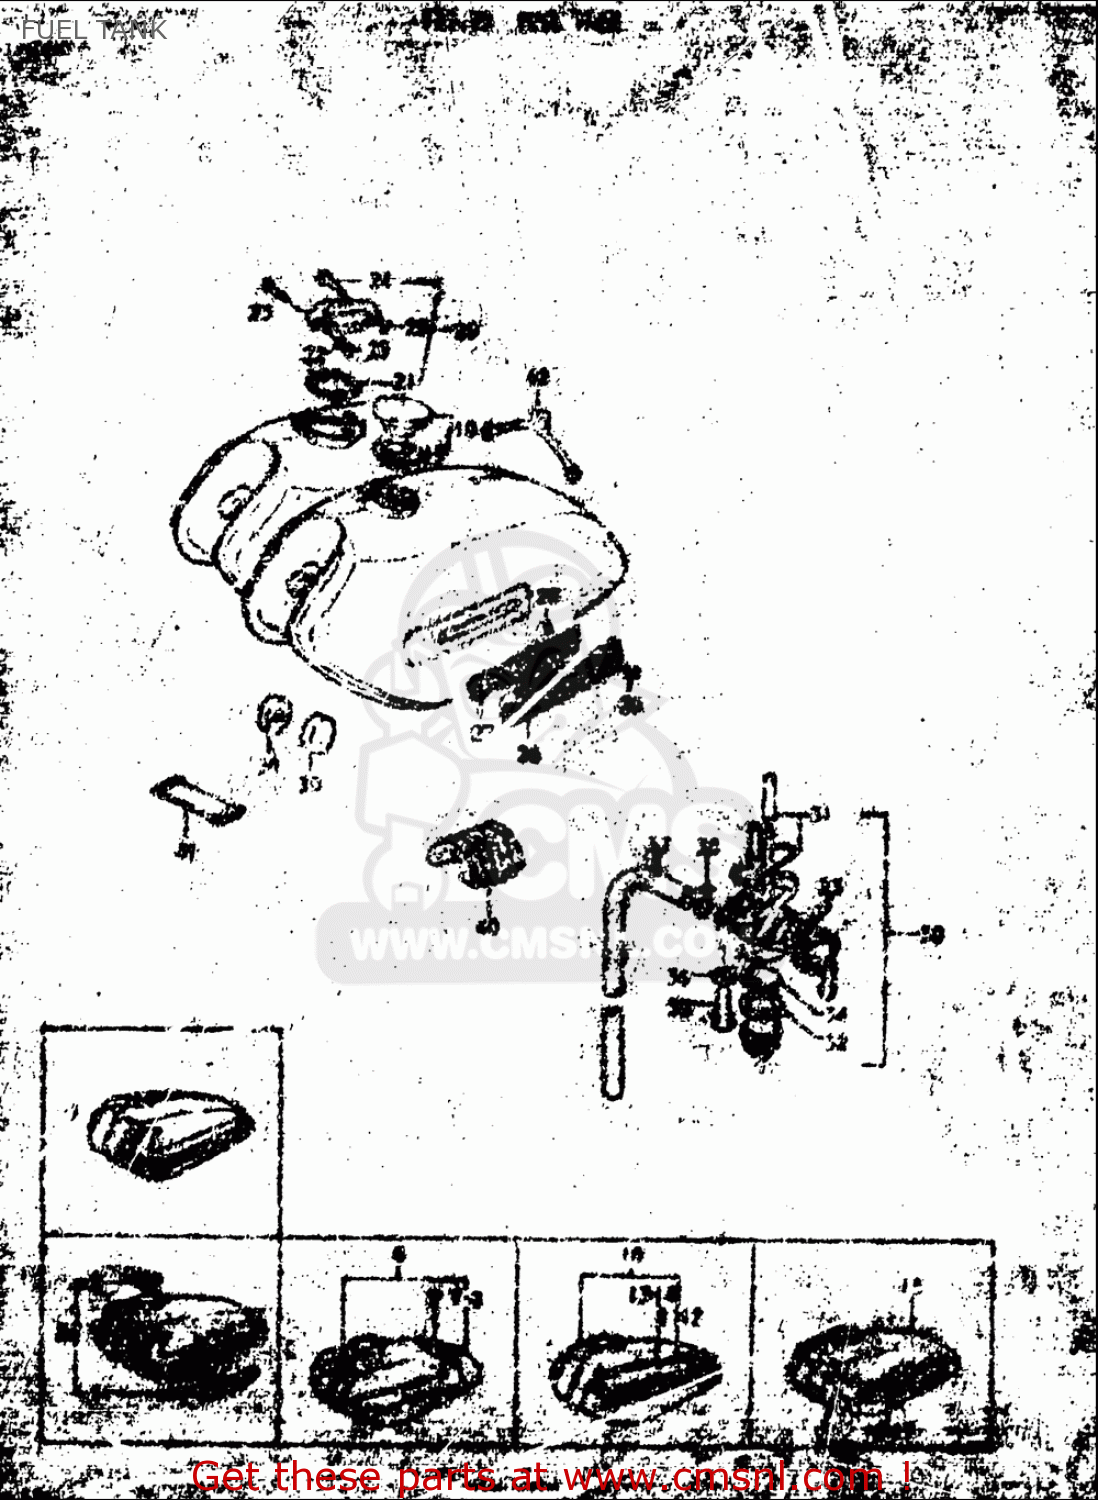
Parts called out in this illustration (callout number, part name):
3	CAP ASSY,FUEL TANK
5	NUT
18	CAP ASSY,FUEL TANK FILLER
20	CAP ASSY,FUEL TANK
21	CAP ASSY,FUEL TANK
22	WASHER
25	E RING
28	SCREW
29	NUT
30	COCK ASSY,FUEL
32	GASKET,FILTER (NAS)
33	GASKET,LEVER (NAS)
35	SCREW
36	GASKET(5.8X13X1.2) (NAS)
37	HOSE(3X7X600)
38	CLIP
39	CUSHION
40	CUSHION
41	BAND
